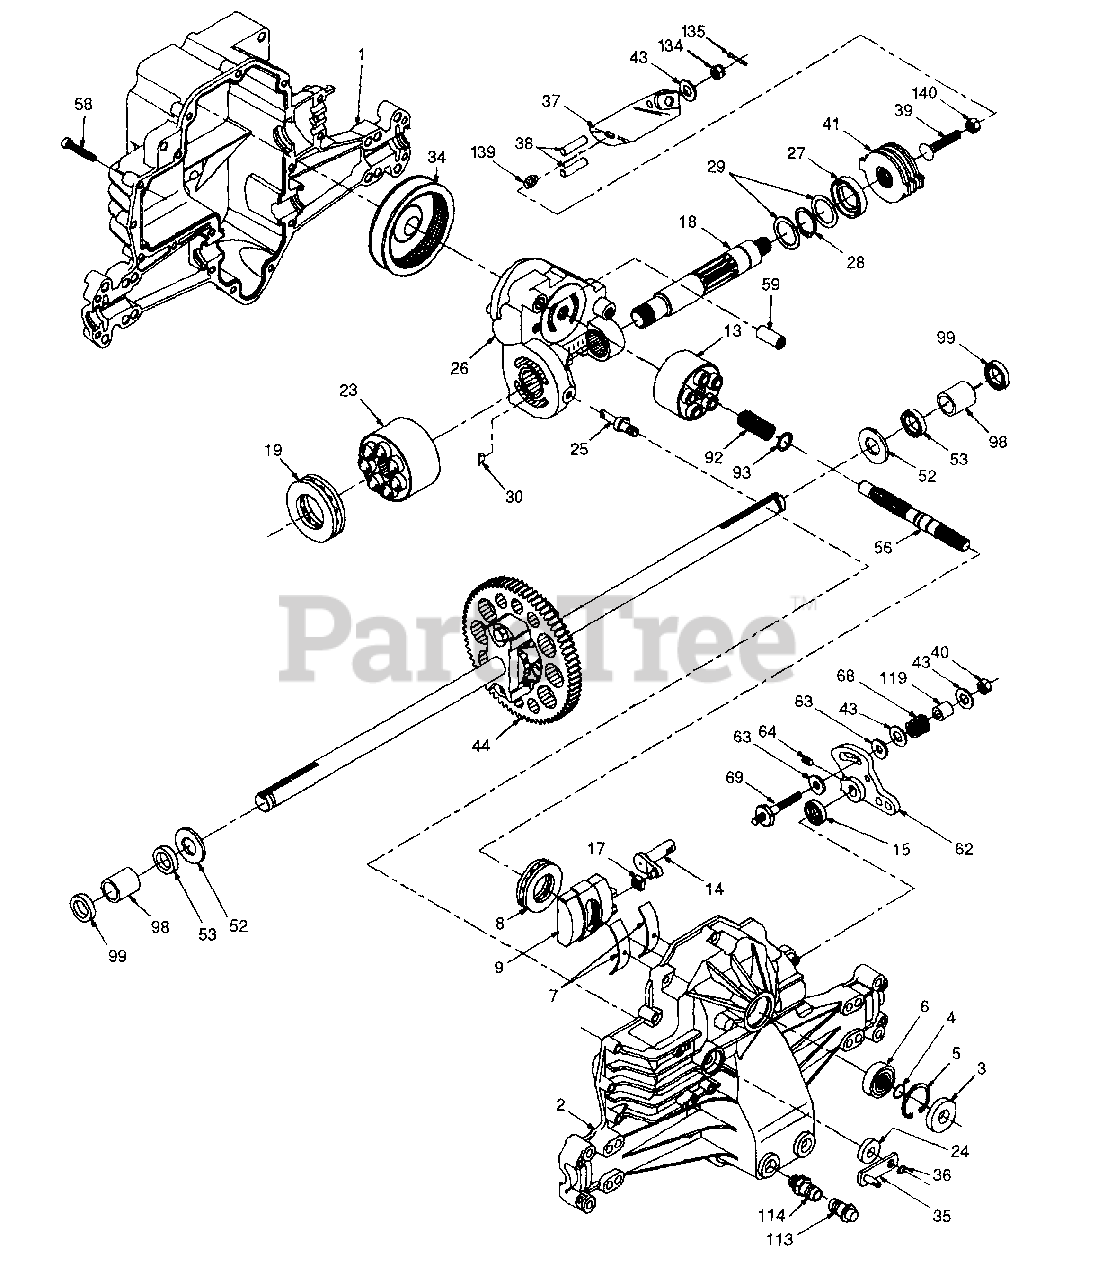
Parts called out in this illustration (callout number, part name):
1	Housing, Lower
2	Assembly, Upper Housing
4	Ring, Wire Retaining
5	Ring, Retaining
6	Bearing, Shaft Ball
7	Bearing, Cradle
8	Bearing, Thrust 30 x 52 x 13
9	Swashplate, Variable
13	Block, Cylinder Assembly
14	Arm, Trunnion
17	Guide, Slot
18	Shaft, Motor
19	Bearing, Thrust 42 x 68 x 16
23	Block, Cylinder Assembly
24	Seal, Lip 10 x 25 x 7
25	Actuator, Bypass
26	Center Section Assembly Kit
27	Seal, Lip 26 x 42 x 8
28	Ring, Retaining
29	Washer 26 x 35 x 1
34	Oil Filter Element
35	Arm, Bypass
36	Ring, Retaining
37	Arm, Actuating
38	Pin, Actuating
39	Bolt 5/16-24 x 1-3/4
40	Locknut, Hex 5/16-24 UNJC
41	Brake Rotor/Stator Kit
43	Washer 7/16 x 7/8 x .060
44	Differential Assembly
52	Washer 3/4 x 1.5 x .13
53	Seal .75 x 1.25 x .250
56	Shaft, Input
58	Bolt 1/4-20 x 1.38
59	Pin .5 OD x .43 ID x .750
62	Arm, Control
63	Puck, Dampener
69	Stud 5/16-24
92	Spring, Block
93	Washer, Block Thrust
98	Sleeve Bearing
99	Seal, Wiper
113	Cap, Vent Assembly
114	Fitting, 0-Ring Assembly
119	Spacer
134	Nut, Castle 5/16-24
135	Pin, Cotter
139	Spring, Compression
140	Nut, Hex 5/16-24
